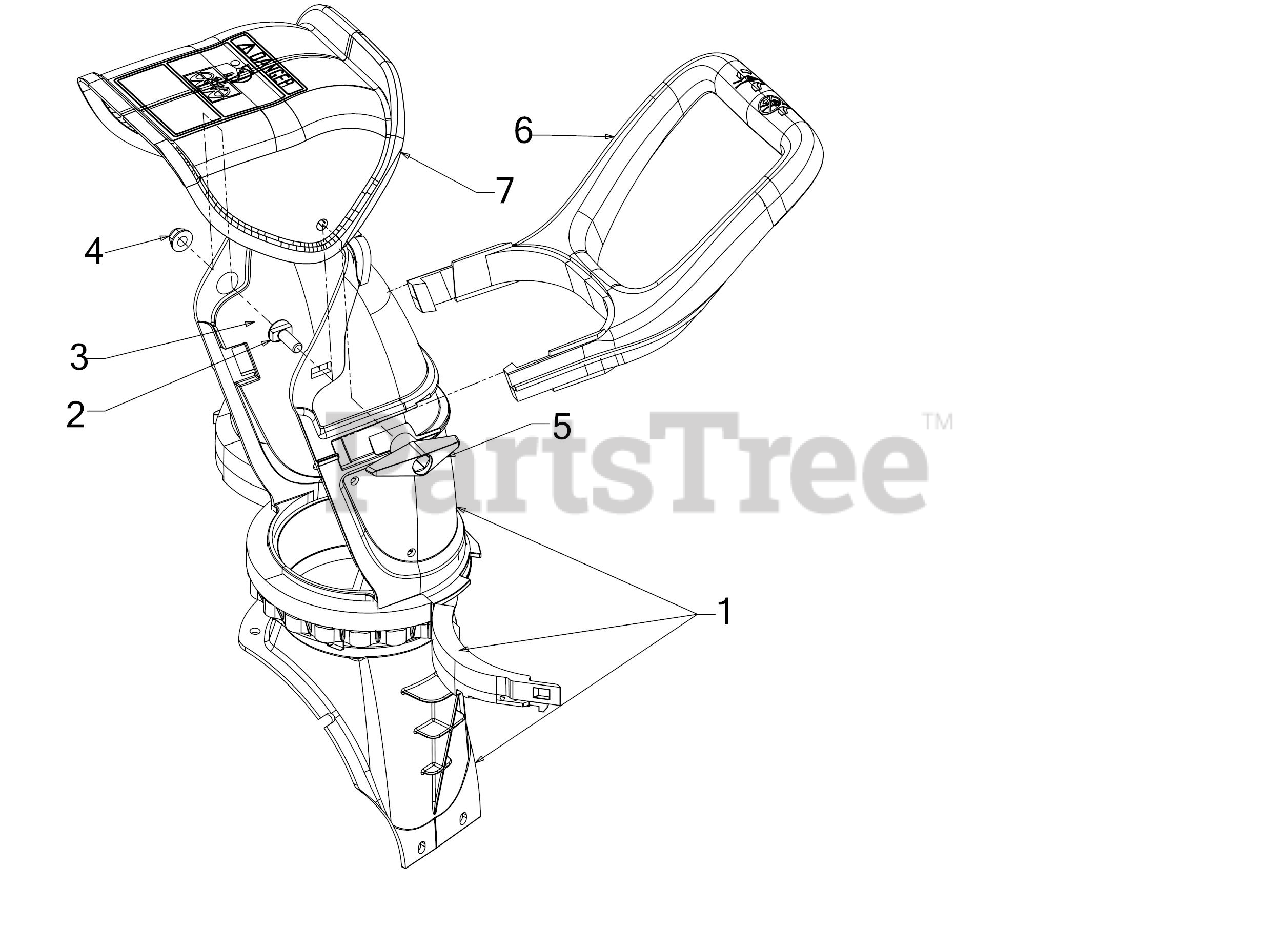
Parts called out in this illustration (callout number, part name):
1	CHUTE ASSEMBLY
2	CARRIAGE BOLT 5/16-18 x 1
3	CARRIAGE BOLT 5/16-18 x .75
4	FLANGE LOCK NUT 5/16-18
5	WING NUT KNOB
6	CHUTE HANDLE
7	UPPER CHUTE
